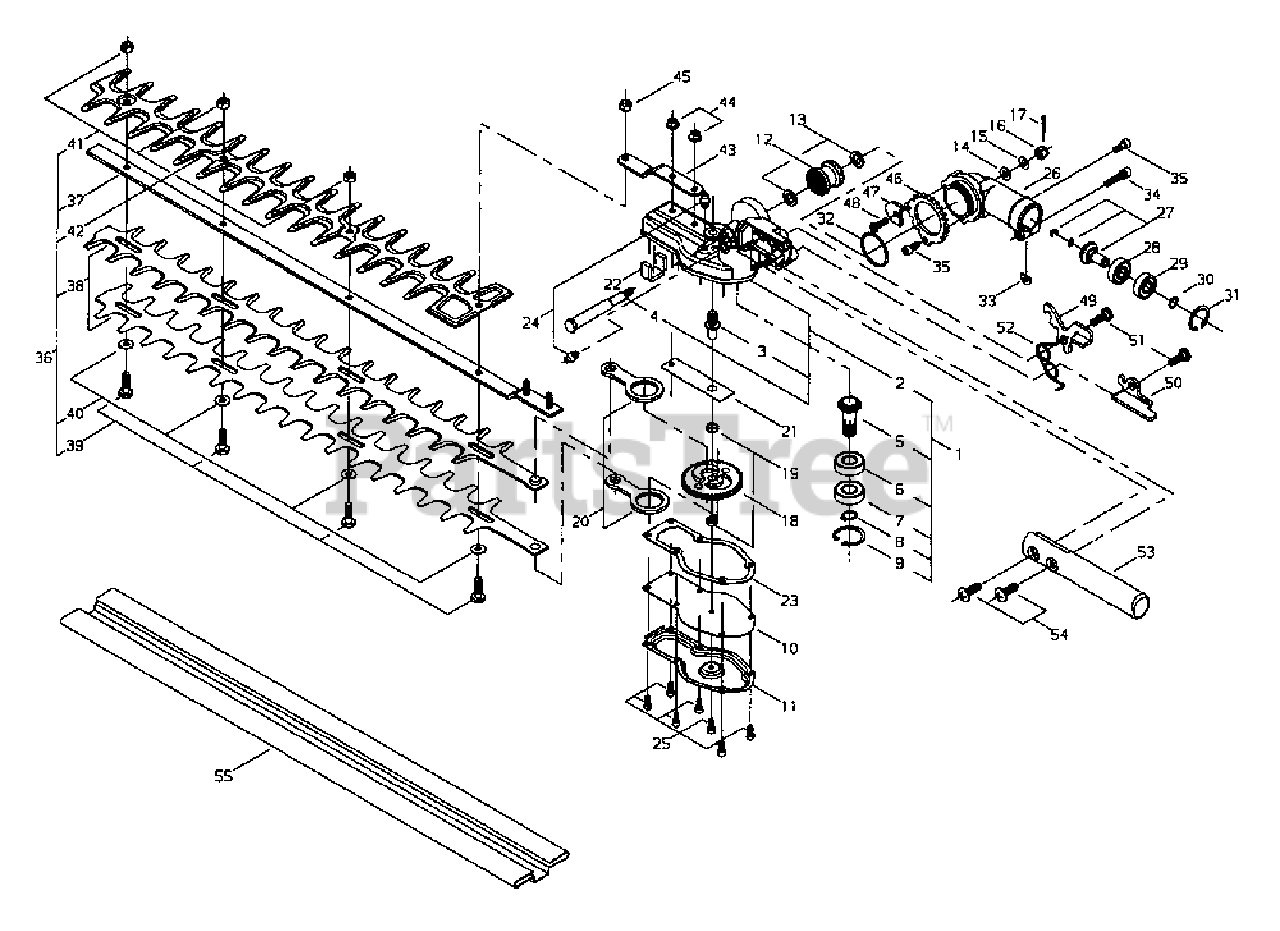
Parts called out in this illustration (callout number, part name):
1	GEAR CASE HOUSING KIT
2	GEAR CASE HOUSING ASSY
3	MAINSHAFT
4	SHAFT
5	SHAFT, PINION
6	BEARING, BALL 6001
7	BEARING, BALL 6001ZZ
8	RING, SNAP Ø12
9	RING, SNAP Ø28
10	SPACER
11	COVER, GEAR CASE
12	GEAR, BEVEL
13	COLLAR Ø16ר10×L= 2
14	WASHER 6.5×13×1
15	WASHER, CONE M6
16	NUT M6
17	PIN, COTTER Ø1.6×15
18	GEAR, CAM
19	SPACER Ø11ר8×3.4
20	CONROD
21	PLATE, GUIDE
22	PACKING, FELT
23	GASKET, GEAR CASE
24	FITTING, GREASE
25	BOLT 4×10
26	HOUSING, UPPER GEAR CASE
27	PINION SET, BEVEL
28	BEARING, BALL 609
29	BEARING, BALL 609ZZ
30	RING, SNAP
31	RING, SNAP Ø24
32	O-RING
33	D-WASHER
34	BOLT M5×25
35	BOLT 5×12
36	CUTTER ASSY, 22" CHROME
37	GUIDE BAR 22"
38	CUTTER, CHROME 22"
39	BOLT M6×20
40	WASHER M6
41	NUT, LOCK M6
42	GUARD, CUTTER BLADE
43	BRACKET, CUTTER
44	NUT, FLANGE M5
45	NUT, LOCK M6
46	RING, LOCKING
47	PLATE, STOPPER
48	SCREW
49	LEVER, LOCK
50	RELEASE, LOCK
51	BOLT M6
52	SPRING, TORSION
53	LEVER, ADJUSTMENT
54	SCREW, TRUSS M6×20
55	SCABBARD
